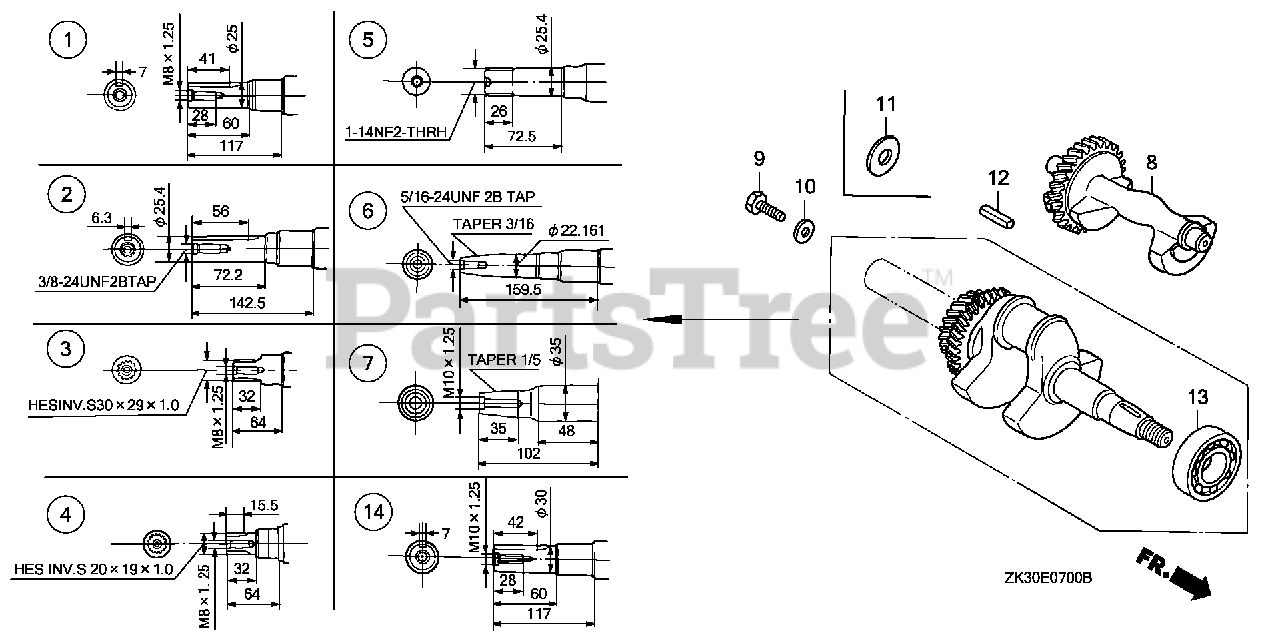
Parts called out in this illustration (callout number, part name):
2	CRANKSHAFT
8	WEIGHT, BALANCER
12	KEY (6.3X6.3X43)
13	BEARING, RADIAL BALL (6207)
